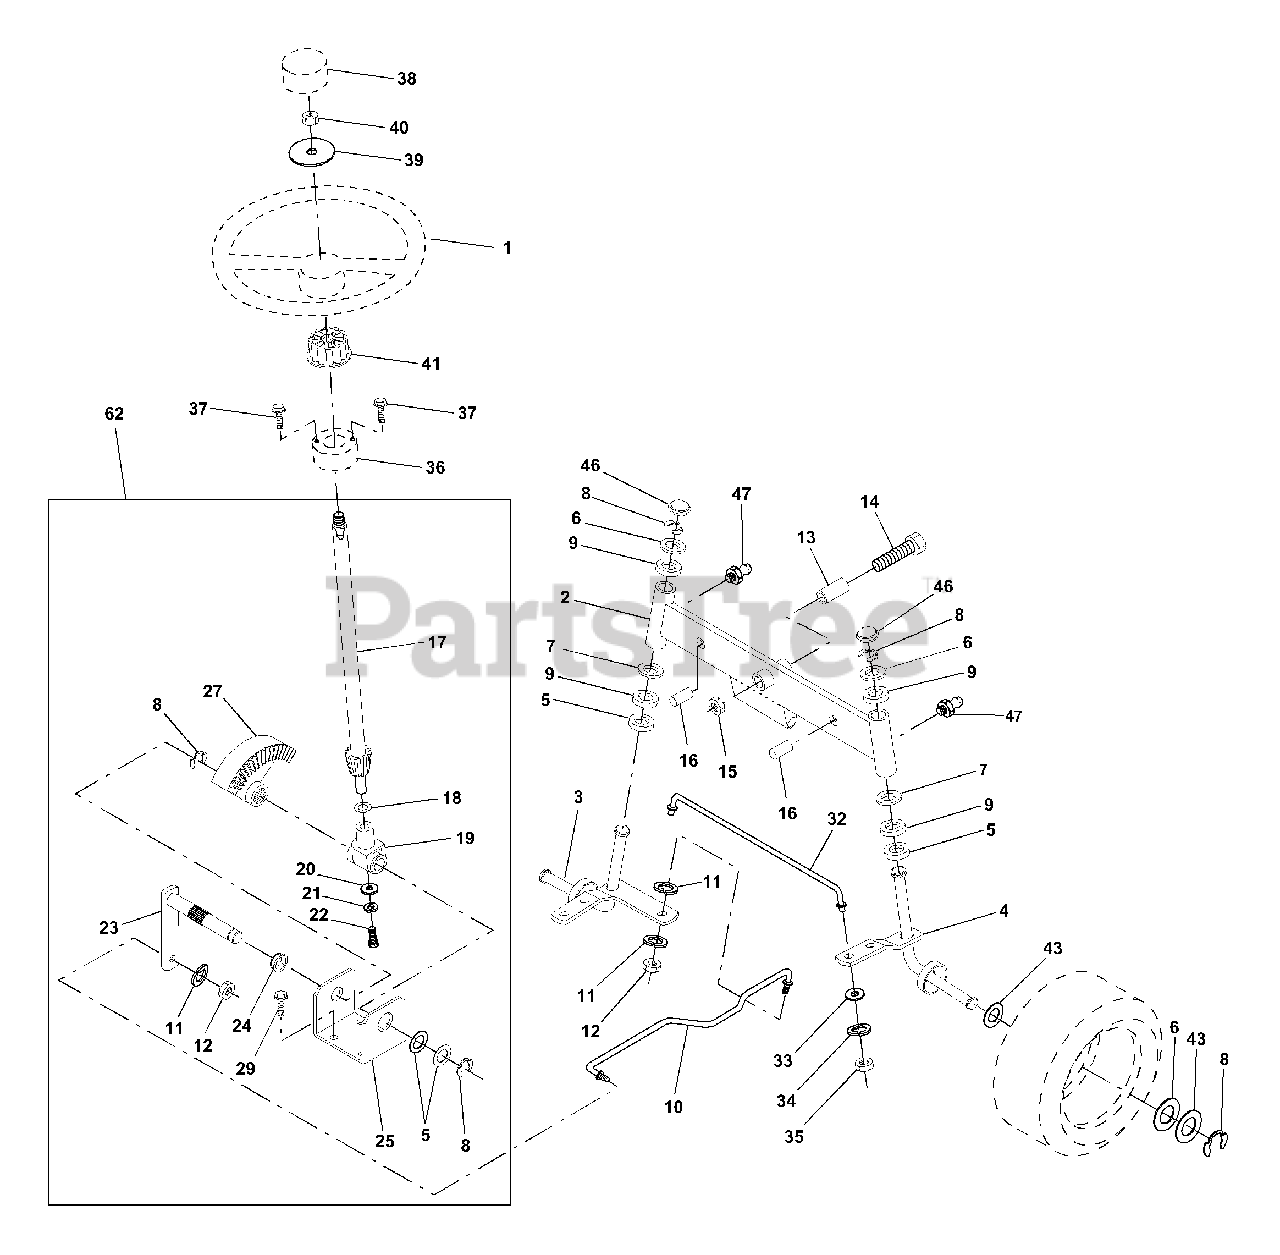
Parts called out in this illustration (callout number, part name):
1	Wheel Steering Auto Grey
2	Axle Asm Fr LT W/gzks 38/42
3	Spindle Asm LH
4	Spindle Asm RH
5	Bearing Race Thrust Harden
6	Washer 25/32 X 1-5/8 X 16 Ga
7	Washer 27/32 X 1-1/4 X 16 Ga
8	Ring Klip #t5304-75
9	Bearing Col Strg Blk
10	Link Drag Sol Ball Jt 20 064
11	Washer Lock Hvy Hlcl Spr 3/8
12	Nut Fin Hex 3/8-24 Unf
13	Spacer Bearing Axle Front
14	Bolt Hex 5/8-11 Unc X 3-1/2
15	Nut Lock Flange 5/8-11 Unc
16	Pin Axle 5/8 X 1 55/1 54 Lg
17	Shaft Asm Strg 20 31 x 3/4 YP YT
18	Washer Thrust 515x 750x 033
19	Support Shaft
20	Washer Shim 1/4 X 5/8 X 062
21	Washer Lock Hvy Helical 1/4
22	Screw Hex Socket 1/4-20 X 5/8
23	Shaft Asm Pittman
24	Nyliner Snap In
25	Bracket Steering
27	Gear Sector
29	Screw Thdrol 3/8-16x3/4 Ty-tt
32	Rod Tie Wire Form 19 75 Elec
33	Washer 11/32 x 3/4 x 16 Ga.
34	Washer, Lock Hvy Hlcl Spr 5/16
35	Locknut 5/16-24 Unf
36	Bushing Strg Angle 3/4"
37	Screw Slftp #10-16 X 1/2 Tt-b
38	Insert Cap Strg Wh Aut Hus Gry
39	Washer 53 X 2 25 X 160 Zinc
40	Nut Hex Jam Toplock 1/2-20 Unf
41	Adapter Wheel Strg 758/ 753id
43	Washer 25/32 X 1 1/4 X 16 Ga
46	Cap Spindle Fr Top Blk
47	Fitting Grease
62	Steering Assembly
